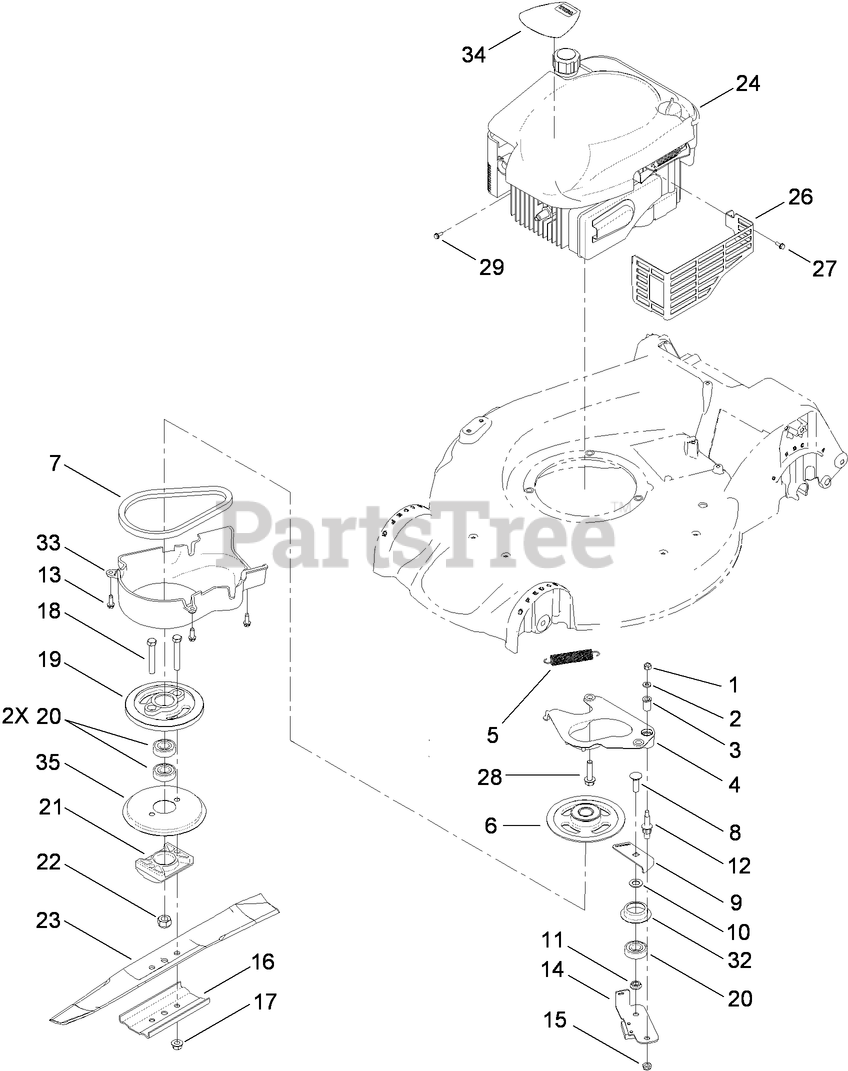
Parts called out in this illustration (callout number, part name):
1	NUT-LOCK, NI
2	WASHER-FLAT
3	BUSHING
4	PLATE-ANCHOR
5	SPRING-TENSION, BRAKE
6	PULLEY
7	BELT
8	BOLT-CARR
9	PLATE-GUIDE
10	SPACER
11	SPACER-BEARING
12	BOLT-SHOULDER
13	SCREW-HWHTF
15	LOCKNUT
16	SUPPORT-BLADE
17	NUT-LOCK
18	SCREW-HH
21	SUPPORT-BLADE
22	NUT-HEX
26	SHIELD-MUFFLER
27	SCREW-TAPTITE
28	SCREW-HWH
29	SCREW-HWH
32	RETAINER-BELT
34	DECAL-SHROUD
35	DISC
